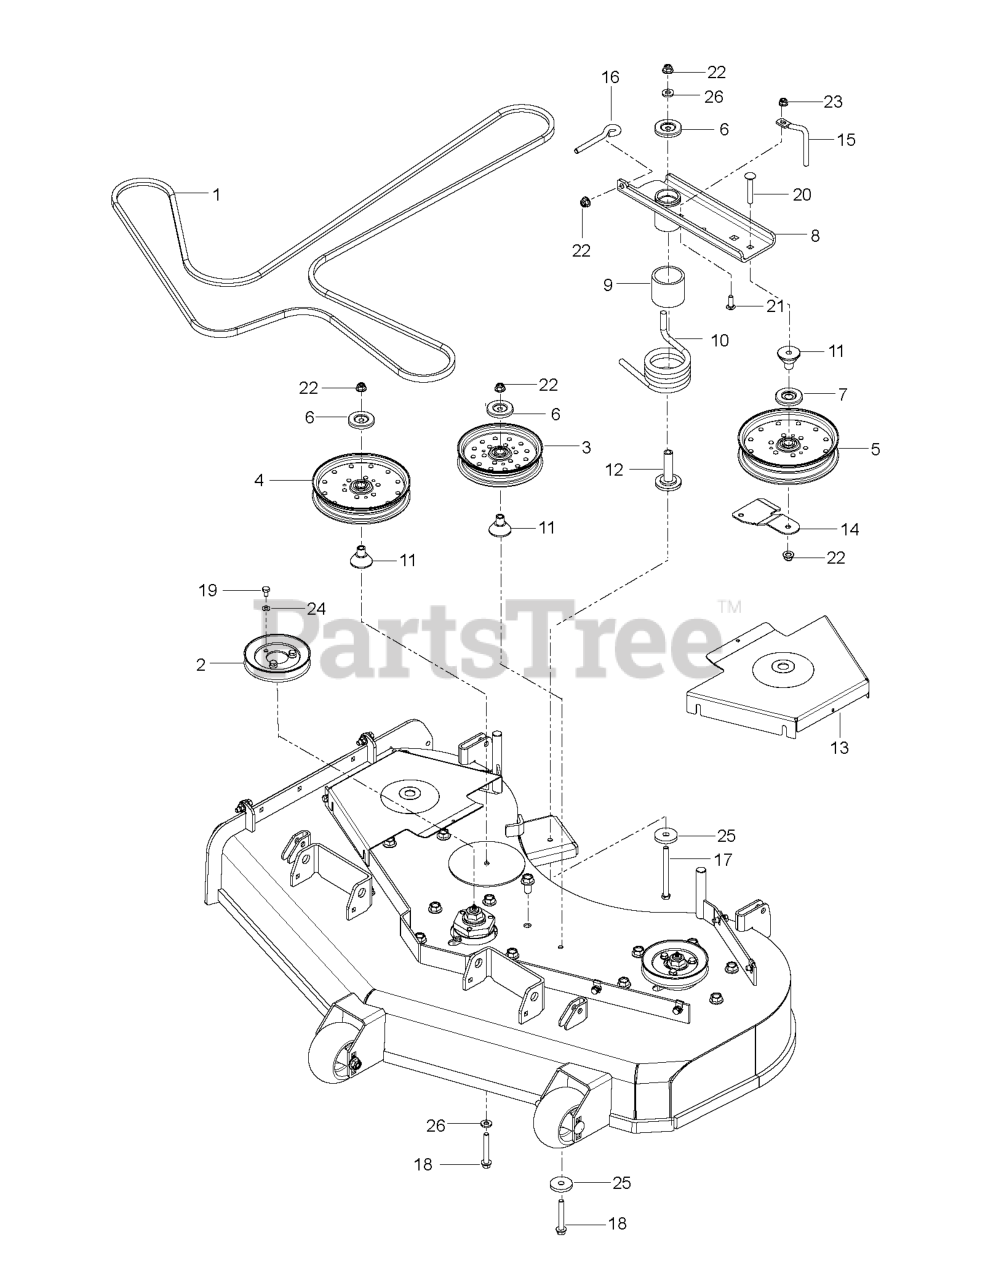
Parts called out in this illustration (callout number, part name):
1	BELT.5V.169.75
2	PULLEY - 5.93 OVER PINS
3	PULLEY - 7" NARROW
4	PULLEY IDLER, 6" NARROW
5	PULLEY - IDLER 7"
6	DUST SHIELD
7	SHIELD, DUST
8	ASSY, IDLER ARM, PZ
9	SPACER, IDLER PIVOT
10	SPRING, TORSION, IDLER
11	BEARING, IDLER ARM
12	BEARING, IDLER PIVOT
13	SHIELD BELT - 60IN SNAPPER RED
14	BELT.GUIDE.BLACK
15	BELT KEEPER
16	EYE BOLT, 3/8 X 4"
17	HCS 3/8-16 X 4-1/2 GR 8 ZD
18	HHFS 3/8-16 X 2-3/4 GR5 ZD
19	HCS 5/16-18 X 1/2 GR 5 ZD
20	CARRIAGE BOLT 3/8-16 X
21	RHSSNB 5/16C X 1.0
22	NUT 3/8-16 HEX FLG NYLOC ZD
23	5/16-18 NYLOC FLANGE NUT
24	WASH 5/16 DISC SPRING ZD
25	SPINDLE WASHER
26	WASHER, 3/8 THICK
